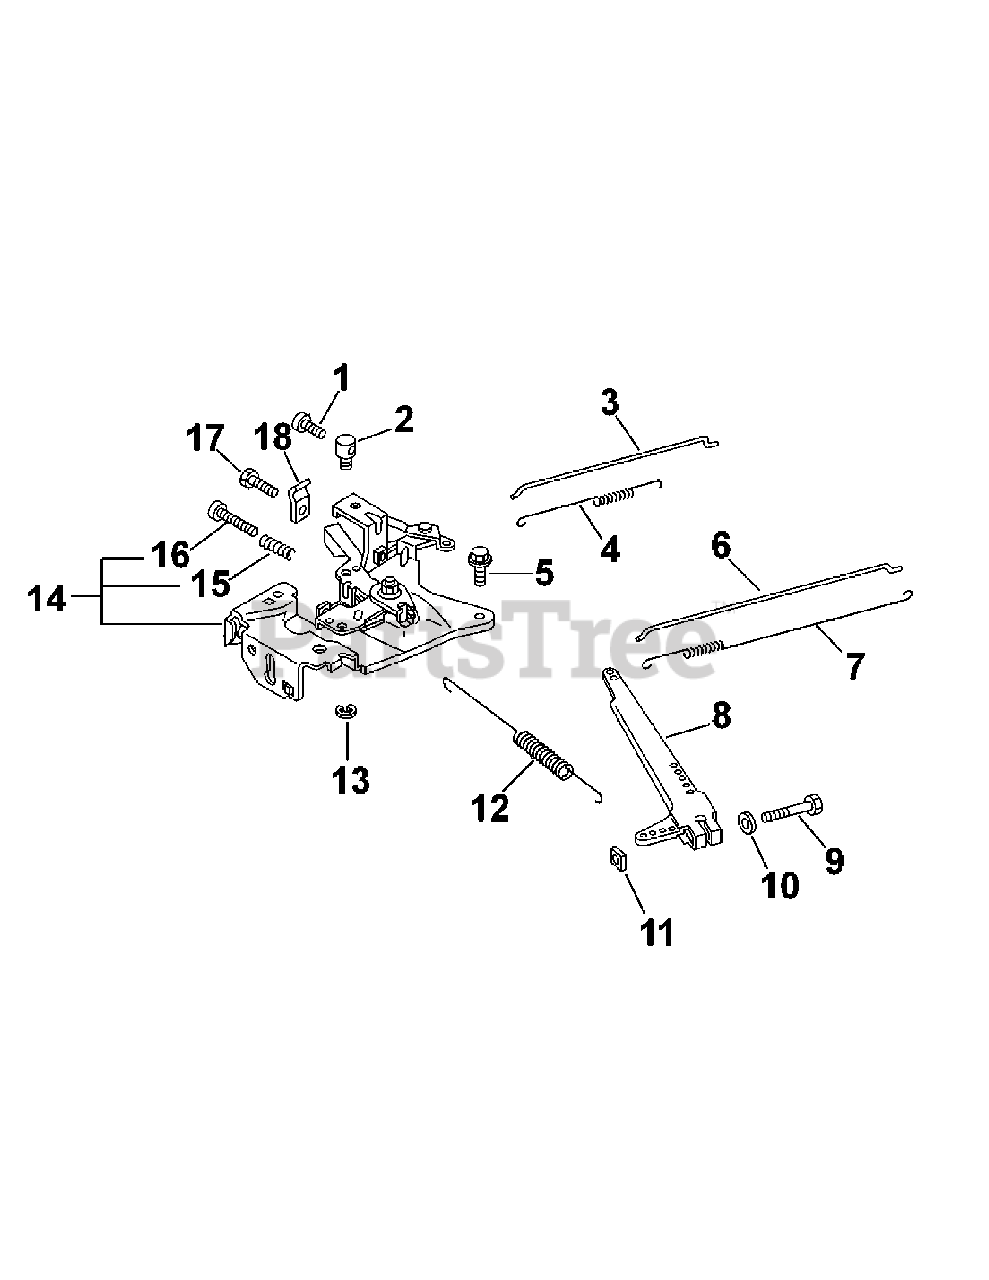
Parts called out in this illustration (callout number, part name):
4	Spring, Linkage
6	Linkage, Throttle
7	Spring, Linkage
8	Lever, Governor
12	Spring, Governor
14	Lever, Throttle
15	Spring, Compression
16	Screw, Pan Head
